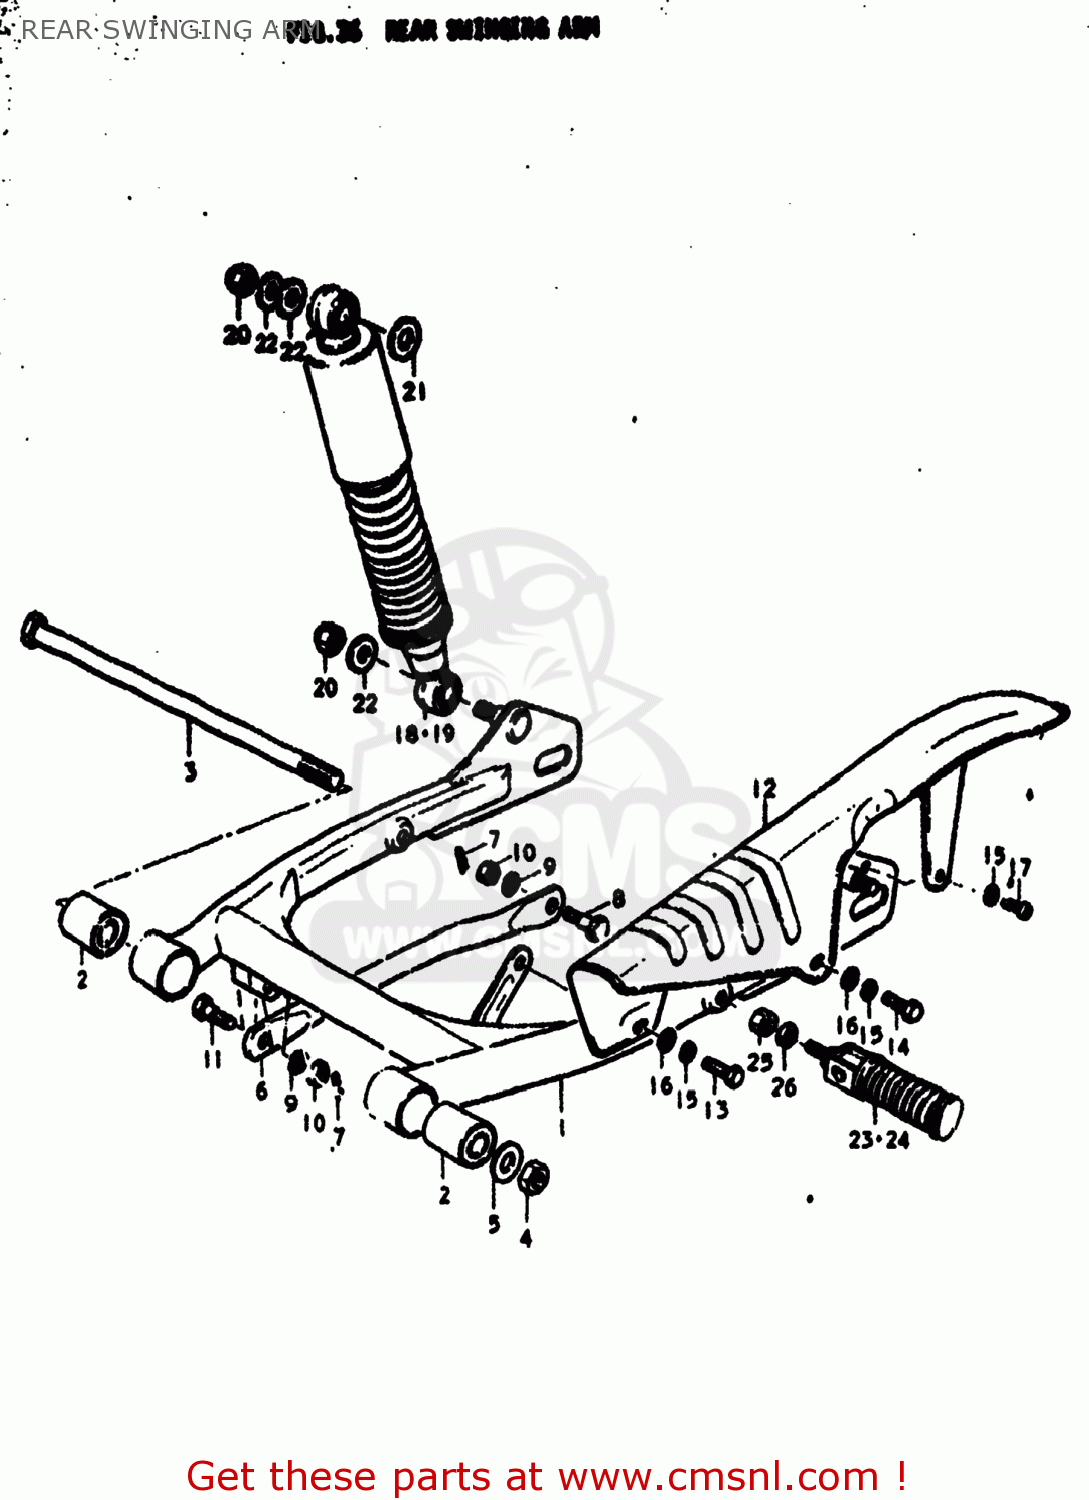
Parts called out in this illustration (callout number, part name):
1	SWING ARM ASSEMBLY,REAR
2	BUSH
3	SHAFT,REAR SWING ARM
4	NUT
5	WASHER(12.5X32X2.3)
6	TORQUE LINK,REAR
7	CLIP
8	BOLT(8X29)
9	LOCK WASHER
10	NUT
11	BOLT(8X26.5)
12	CASE,CHAIN
13	BOLT
14	BOLT(6X8)
15	LOCK WASHER
16	WASHER
17	SCREW
18	ABSORBER ASSEMBLY,REAR SHOCK
19	ABSORBER ASSEMBLY,REAR SHOCK
20	NUT
21	WASHER
22	WASHER
23	FOOTREST ASSEMBLY,REAR
24	FOOTREST ASSY,PILLION
25	NUT
26	WASHER,LOCK 12
